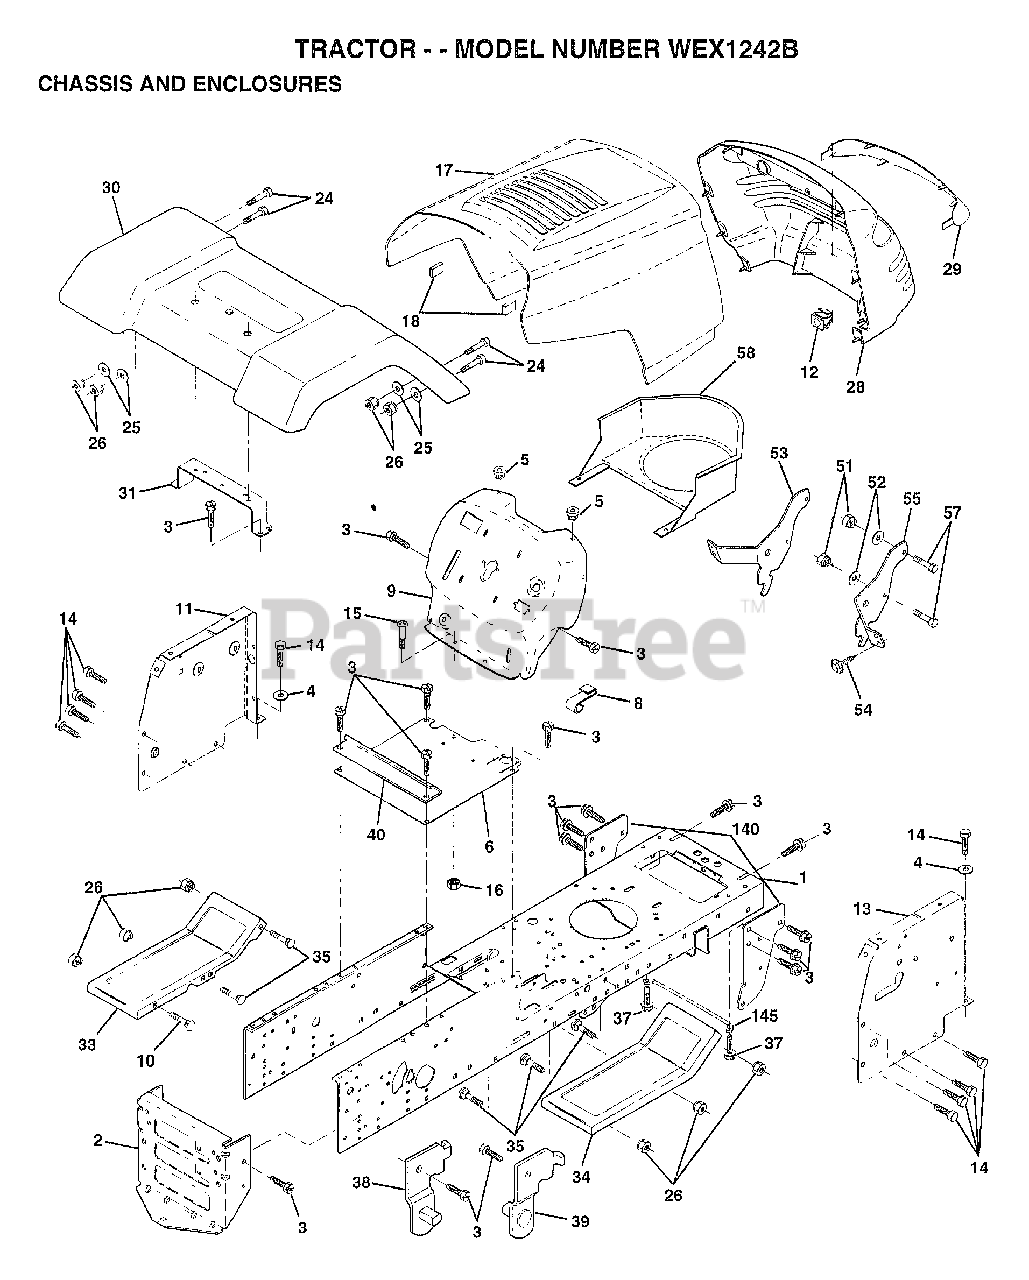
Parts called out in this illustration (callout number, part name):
1	CHASSIS.STAMPING
3	SCREW
4	WASHER
5	BUMPER-HOOD/DASH
6	SADDLE
8	CLIP.RETAINER
9	DASH SILKSCREEN
11	"PANEL-DASH,LH"
12	CLIP.TINNERMAN
14	SCREW LT
15	SCREW
17	HOOD.STEEL.ASSY
24	BOLT
25	WASHER
26	NUT
28	GRILLE-MS428
29	LENS.GRILLE.PRIVATE LABEL
31	BRKT FENDER
33	FOOTREST.LH.PERF.
34	FOOTREST.RH.PERF.
35	BOLT
37	SCREW LT
38	BRACKET ASM LH
39	BRACKET ASM RH
51	NUT
52	WASHER
53	BRACKET.GRILLE.LH
54	SCREW.HEX.WS.HD
55	BRACKET.GRILLE.RH
58	AIR DUCT
140	BRKT SUSPENSION
145	"ROD POVOT,CHASSIS"
